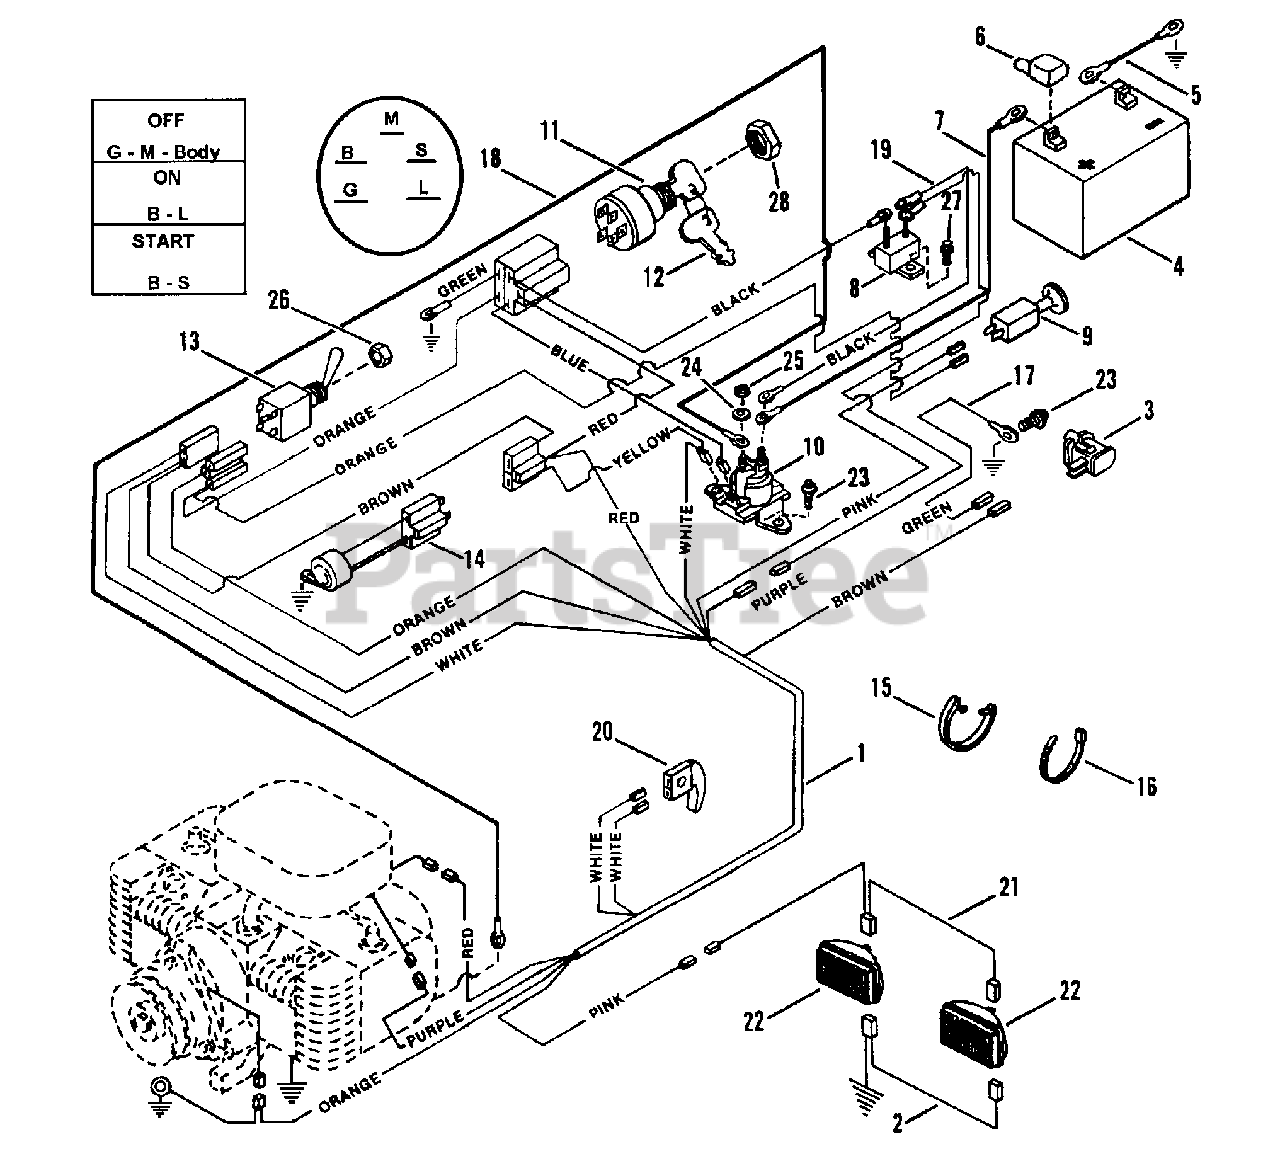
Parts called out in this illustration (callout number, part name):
1	HARNESS, Wiring - B&S
1	HARNESS, Wiring - Kohler
2	HARNESS, Ground
3	SWITCH, Seat Interlock (NO)
4	KIT, Battery 12 Volt, 20 AMP HR
5	CABLE, Negative
6	COVER, Positive Terminal
7	CABLE, Solenoid to Batt. (11")
8	CIRCUIT-BREAKER
9	SWITCH, Headlamp
10	SOLENOID
11	KEYSWITCH
12	KEY (Set of 2)
13	SWITCH, PTO
14	MODULE, Interlock - B&S
14	MODULE, Interlock - Kohler
15	TIE, Wire
16	TIE, Cable
17	WIRE, Seat Switch to Ground
18	CABLE, Solenoid/Starter (36")
19	WIRE, Breaker to Solenoid
20	SWITCH, Clutch Interlock
21	HARNESS, Headlamp
22	HEAD-LAMP
23	SCREW, 1/4-20 X 5/8" Hex Washer Self-Tap
24	WASHER, 1/4 Int. Tooth Lock
25	NUT, 1/4-20 Hex
26	NUT, Special 1/2-27 Hex
27	SCREW, #10-24 x 1/2" Hex Washer Self-Tap (Torx)
28	NUT, Special 5/8-32 Hex
